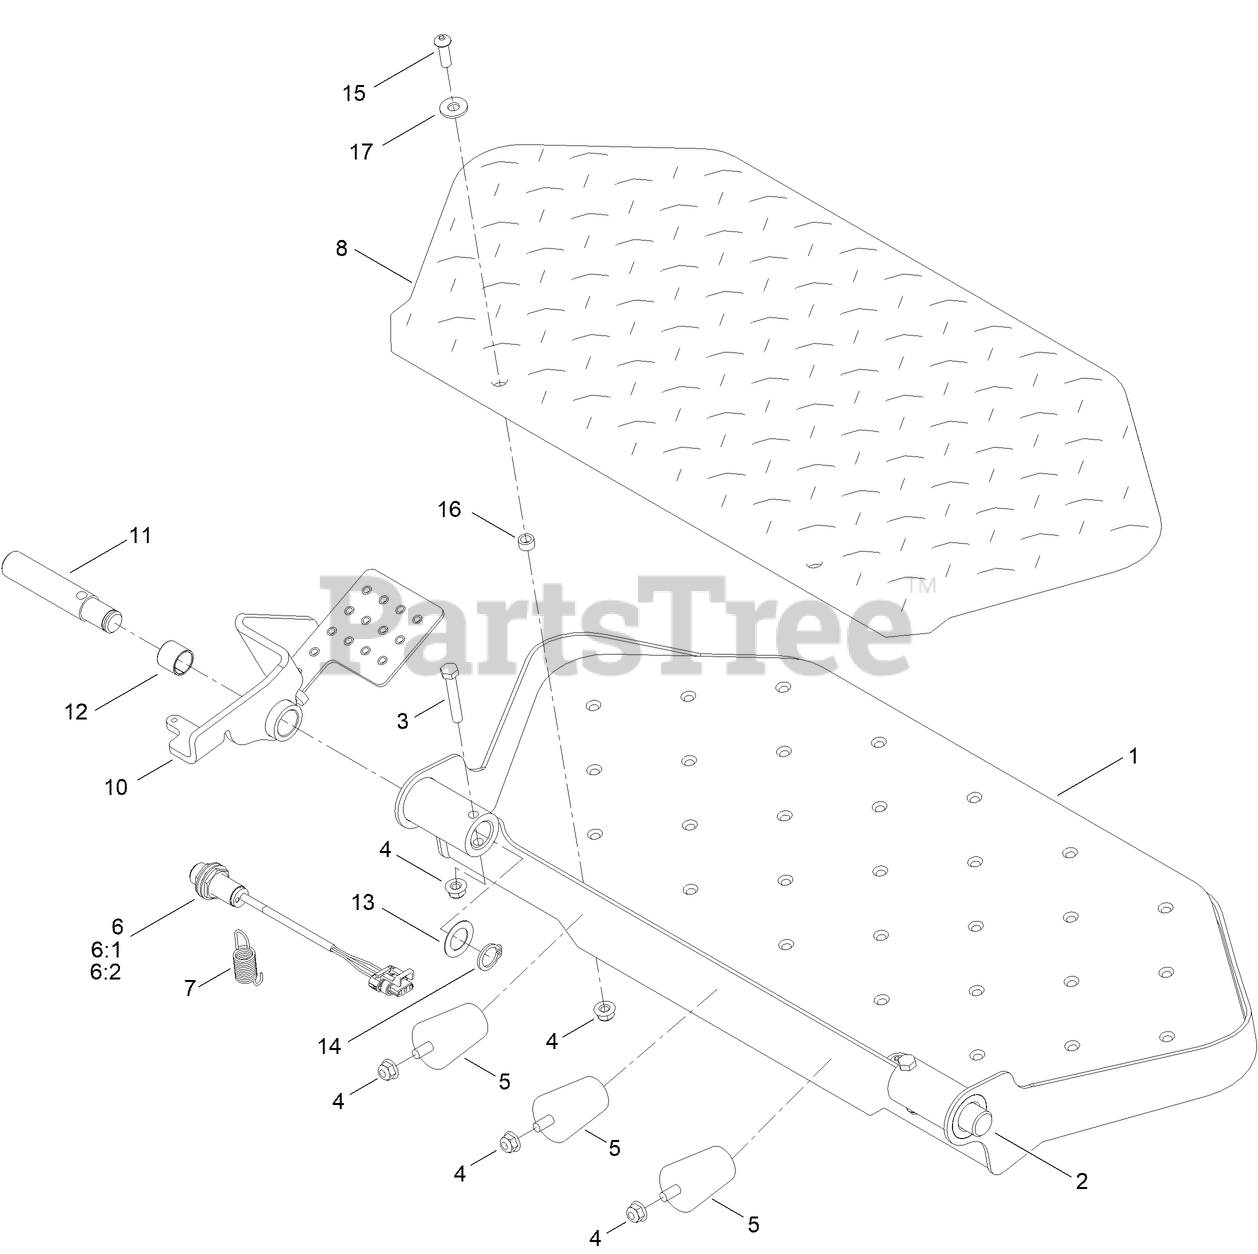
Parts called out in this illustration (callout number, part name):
1	PLATFORM ASM [BLACK]
2	PIN-PIVOT
3	SCREW-HH
4	NUT-HF, NI
5	BUMPER
6	PROXIMITY SWITCH ASM
6:1	NUT-HEX
6:2	WASHER-LOCK, INTERNAL TOOTH
7	SPRING-EXTENSION
8	PAD-PLATFORM
10	FOOT PEDAL ASM, [BLACK]
11	PIN-PIVOT
12	BUSHING-STRAIGHT
13	WASHER-FLAT
14	RING-RETAINING
15	SCREW-HSBH
16	SPACER-PIVOT, TILT
17	WASHER-FLAT
